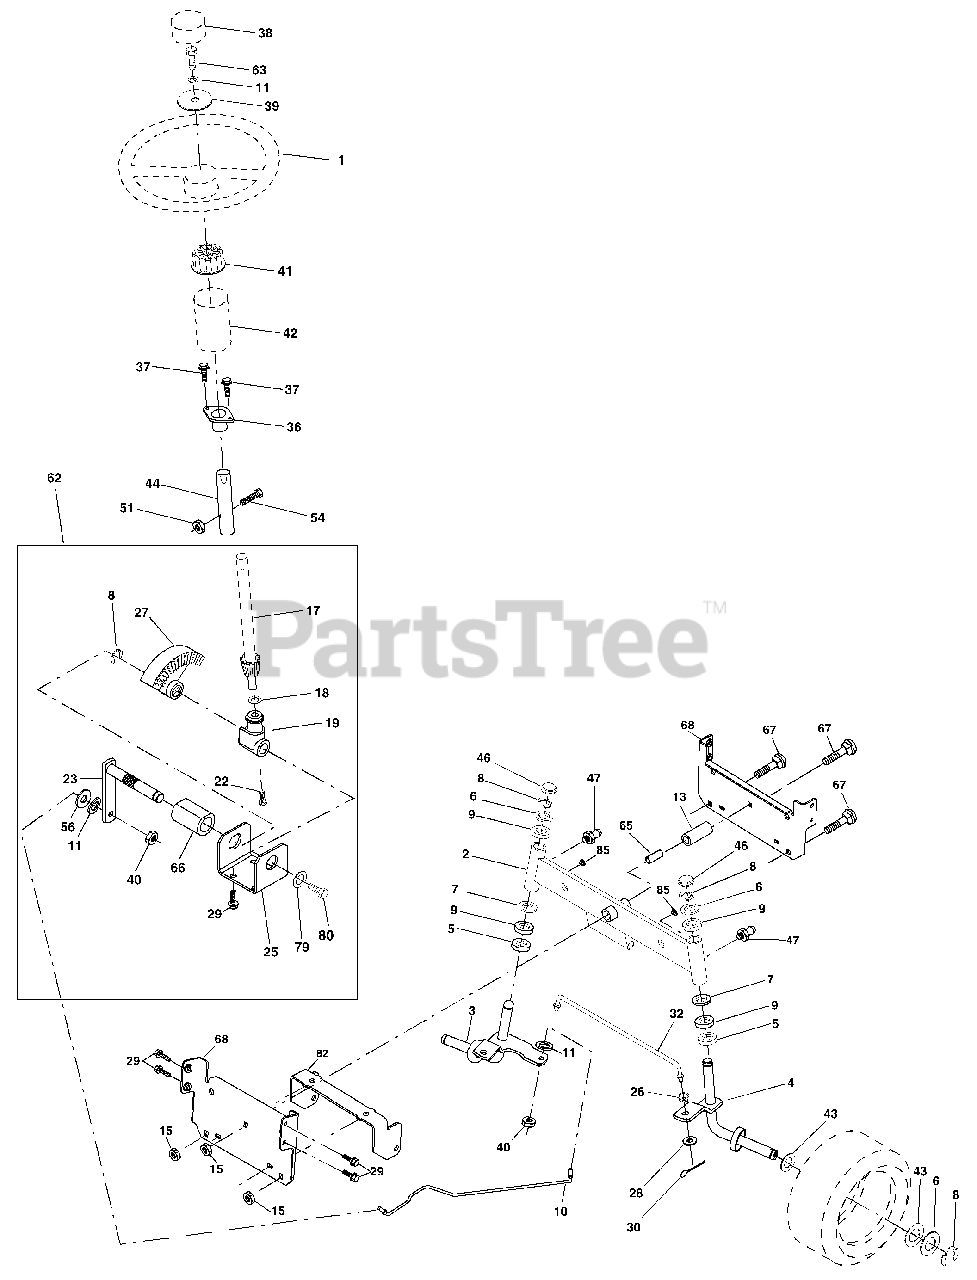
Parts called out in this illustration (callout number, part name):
1	Wheel Steering Auto Black
2	Axle Asm Front
3	Spindle Asm Lh
4	Spindle Asm Rh
5	Bearing Race Thrust Harden
6	Washer 25/32 X 1 5/8 X 16ga
7	Washer 27/32 X 1 1/4 X 16 Ga
8	Ring Klip #t5304-75
9	Bearing Col Strg Blk
10	Link Drag
11	Lockwasher
13	Spacer Bearing Axle Front
15	Nut Hex Flange Lock
17	Shaft Asm Strg 5/8 X 15 19 Lt
18	Washer Thrust 515 x 750 x 033
19	Support Shaft
22	Screw Hex Wsh Hd Torx
23	Shaft Asm Pittman
25	Bracket Steering
26	Bushing Rod Tie Blk Lt
27	Gear Sector
28	Washer 13/32 X 7/8 X 16ga
29	Screw 3/8-16 x 3/4
30	Pin
32	Rod Tie Wire Form 19 75 Mech
36	Bushing Strg 5/8 Id Dash
37	Screw TT #10-32 x 5 x 3/8 Flange
38	Insert Cap Strg
39	Washer 13/32 X 2-3/8 X 12 Ga
40	Locknut Center
41	Adaptor Wheel Strg 640/ 635 id
42	Boot Dash Steering
43	Washer 25/32 X 1 1/4 X 16 Ga
44	Extension Steering Non-Adjust
46	Cap Spindle Fr Top Blk
47	Fitting Grease
51	Nut Lock Hex W/Ins.
54	Bolt Fin Hex 5/16-18 Unc P
56	Washer 13/32 x 3/4 x 10 Ga.
62	Kit Steering Assembly Service
63	Bolt Fin Hex 3/8-16unc x Gr. 5
65	Spacer Axle
66	Bearing Arm Pittman
67	Bolt Rdhd Sq 3/8-16 Unc x 2-1/4
68	Brace Axle
79	Washer 13/32 x 1-1/4 x 12 Ga.
80	Bolt Hex Nylon 3/8-16 x 3/4
82	Bracket Susp Chassis Front
85	Fastner Christmas Tree
